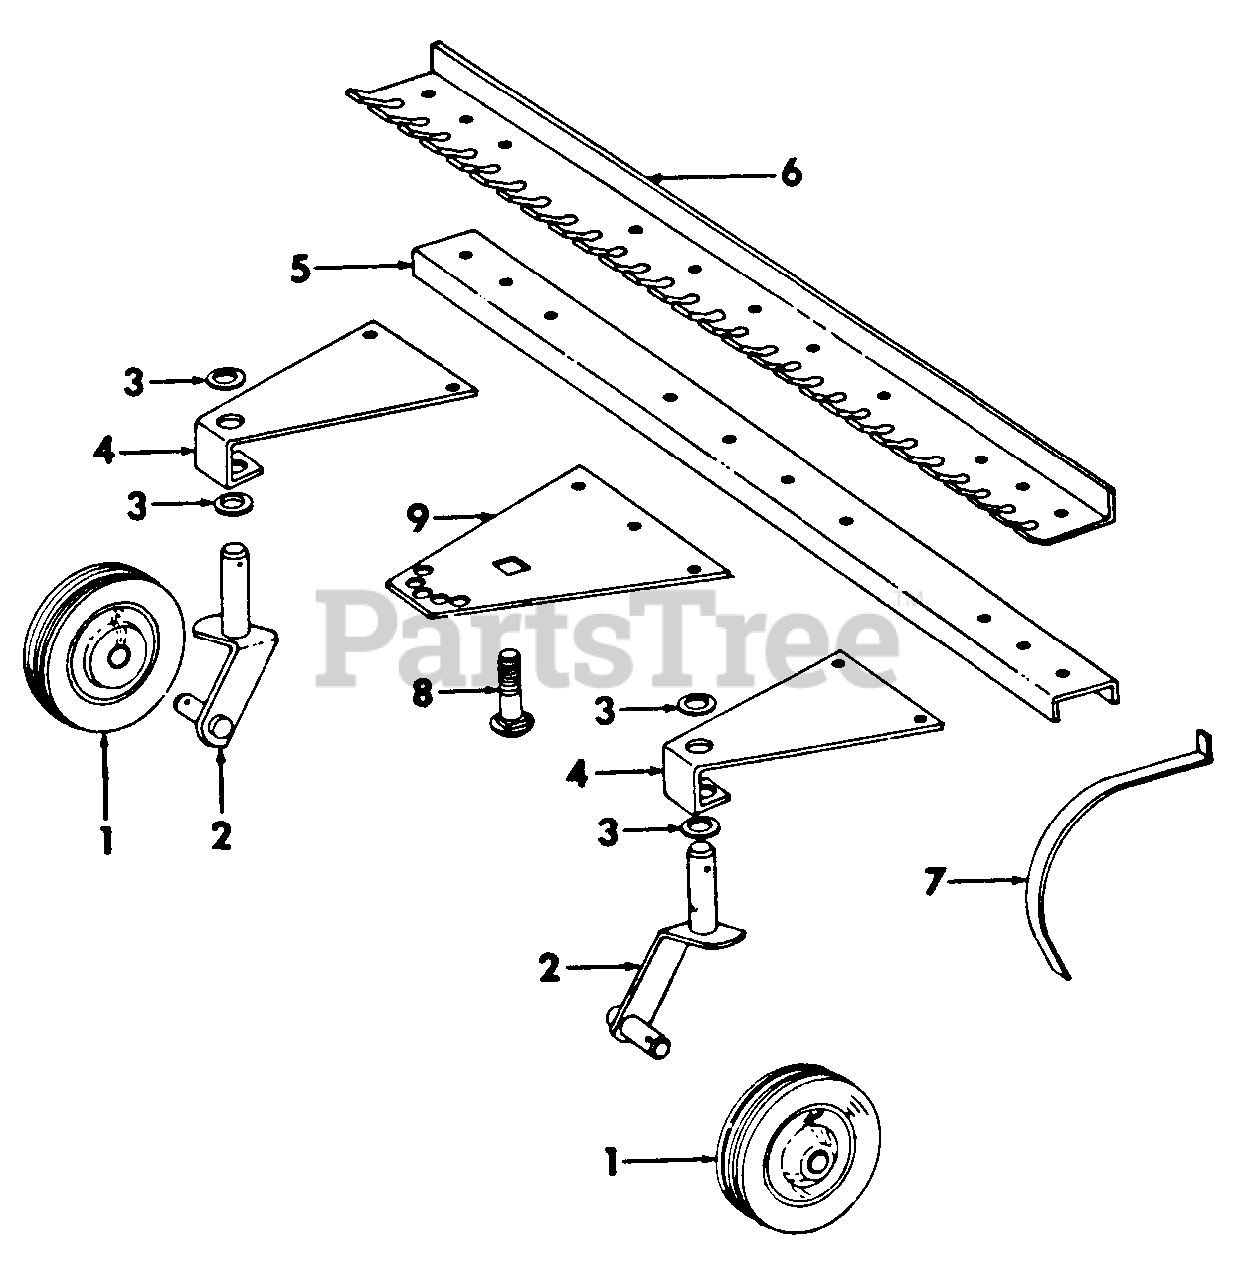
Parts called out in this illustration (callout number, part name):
1	Wheel Assy, Gage
2	Carrier Assy, Rake Gage Wheel
3	Washer, 15/16 X 1-3/4 X .134 C-Z -Gage Wheel Height Adjusting Washer
4	Bracket, Gage Wheel
5	Channel, Tooth Attaching
6	Guide, Tooth Attaching
7	Tooth, Tiller Rake
8	Bolt, 7/8-9 X 3-1/2 C-Z Drd Sq-Nk Crg
9	Plate, Rake Adjusting
